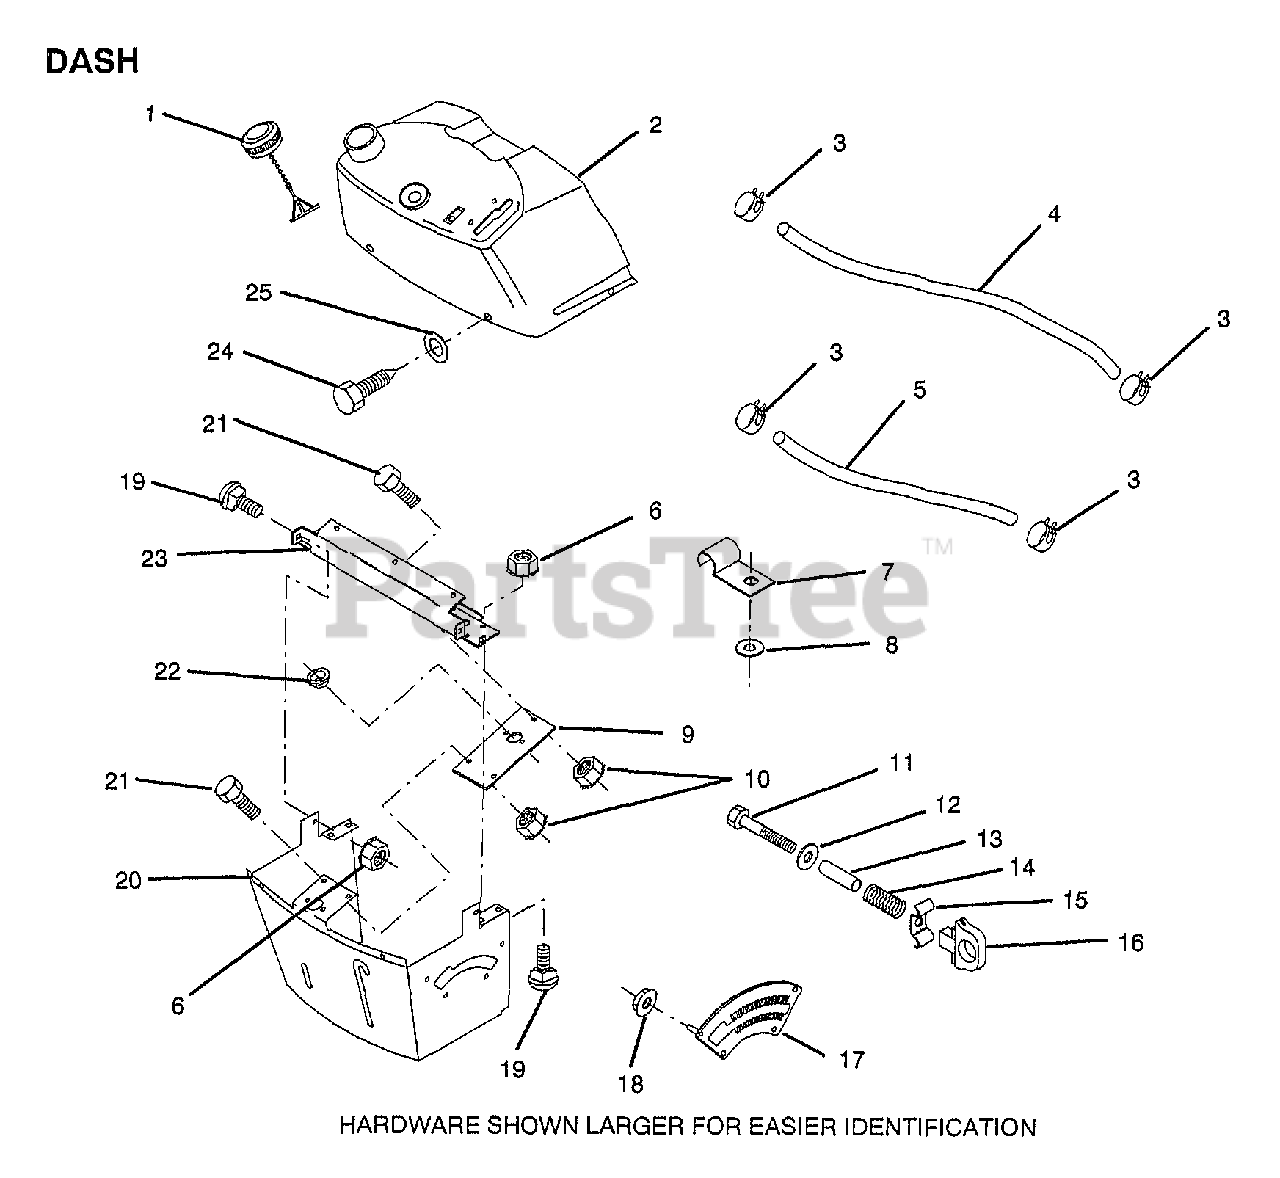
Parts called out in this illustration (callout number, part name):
3	HOSE CLAMP
5	FUEL LINE T
6	NUT
7	CLIP T
8	WASHER PM
9	"PLATE,SUPT "
10	LOCKNUT
11	BOLT
12	WASHER
13	SPACER SPLIT
14	SPRING T
15	HEIGHT ADJ
16	KNOB
17	ADJUSTER QUAD
18	NUT
19	BOLT
20	SUPPORT DASH
23	"BRAKE,CROSS"
